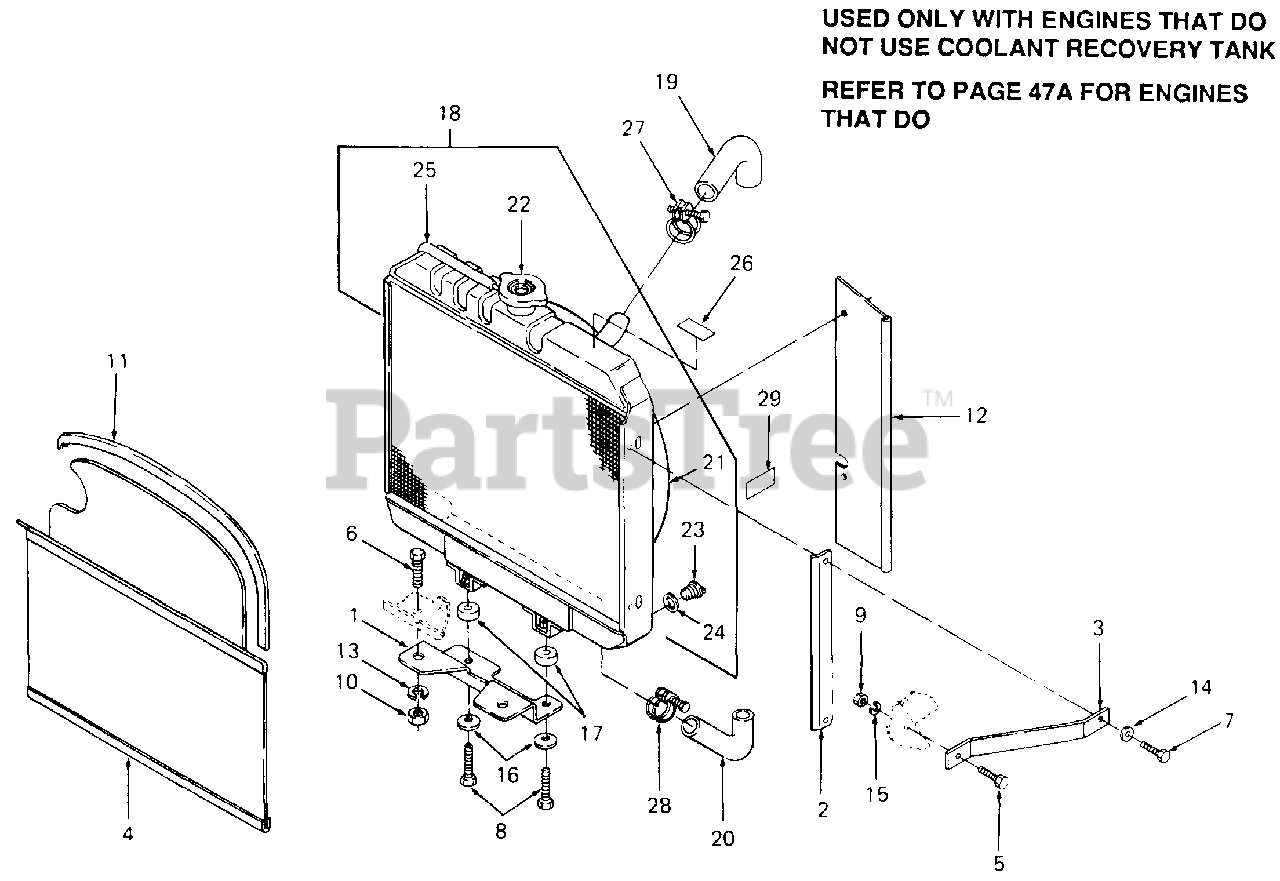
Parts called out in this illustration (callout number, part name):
1	Mount, Radiator
2	Track, Screen
3	Brace, Radiator
4	Heat Baffle Assy
5	Screw, Hex Cap, 1/4-20 X .62 Lg GR5
6	Screw, Hex Cap, 5/16-18 X .75 Lg GR5
7	Screw, Hex Cap, M6 X 14 mm Lg GR5
8	Screw, Hex Cap, M10 X 30 mm Lg GR8
9	Nut, Hex, 1/4-20 GR5
10	Nut, Hex, 5/16-18 GR5
11	Strip, Trim
12	Flap, Radiator Air
13	Washer, Lock, 5/16 Dia
14	Washer, Bell, .265 X .75 X .062
15	Washer, Lock, 1/4 Dia
16	Washer, Bell, .45 X 1.0 X .062
19	Radiator Hose, Upper
20	Radiator Hose, Lower
25	Pipe, Water Overflow
26	Label, Radiator
29	Label, Antifreeze
